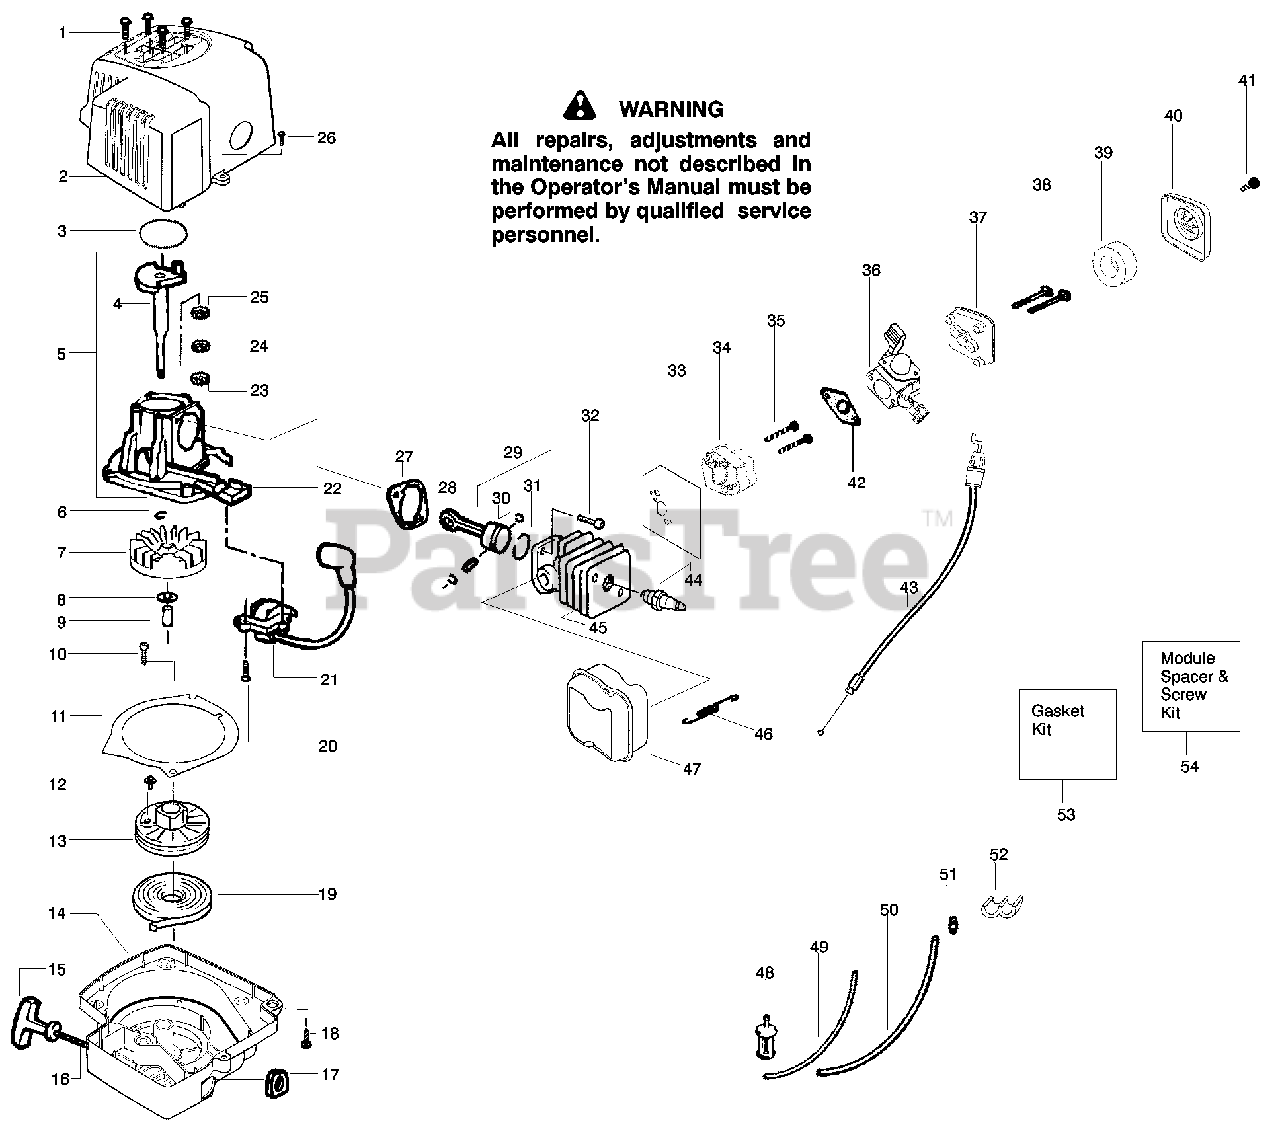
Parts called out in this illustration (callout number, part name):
2	Assy-Shroud
3	O-Ring-Shrd (kit)
4	Assy-Crankshaft
5	Assy-C/case-C/shaft
6	Ring-Retainer-C'shaft
7	Assy-Flywheel
8	Washer-Flat
9	Spacer-Flywheel
11	Plate-Baffle
13	Kit-Starter Pulley
14	Assy-Fan Housing
15	Handle-Starter
16	Kit-Rope
17	Grommet-Ignition Module
18	Screw-(f/hsg to shrd)
19	Spring-Starter
21	Ignition Module GHT 180/220 (USA only)
21	Ignition Module GHT 220 (Canada only)
22	Assy-Crankcase
23	Bearing-Outer
24	Kit-Crankcase Seal
25	Bearing-Inner
27	Gasket-Cylinder (kit)
28	Assy-Connecting Rod
29	Kit-Piston
30	Retainer-Piston Pin
31	Ring-Piston
33	Gasket-Carb. Adapt. (kit)
34	Adapter-Carburetor
36	Kit-Carburetor Ass'y. (C1U-W13A)
39	Air Filter Foam
40	Air Filter Cover
42	Gasket-Carburetor (kit)
43	Assy-Throttle Cable
44	Spark Plug(RCJ-6Y)
45	Kit-Cylinder
46	Spring-Muffler
47	Kit-Spark Muffler
48	Assy-Pick-up
49	Kit-Fuel Line(small)
50	Kit-Fuel Line(large)
51	Fitting-Fuel Line
52	Clip-Retainer
53	Kit-Gasket
54	Kit-Module Spacer & Screws
